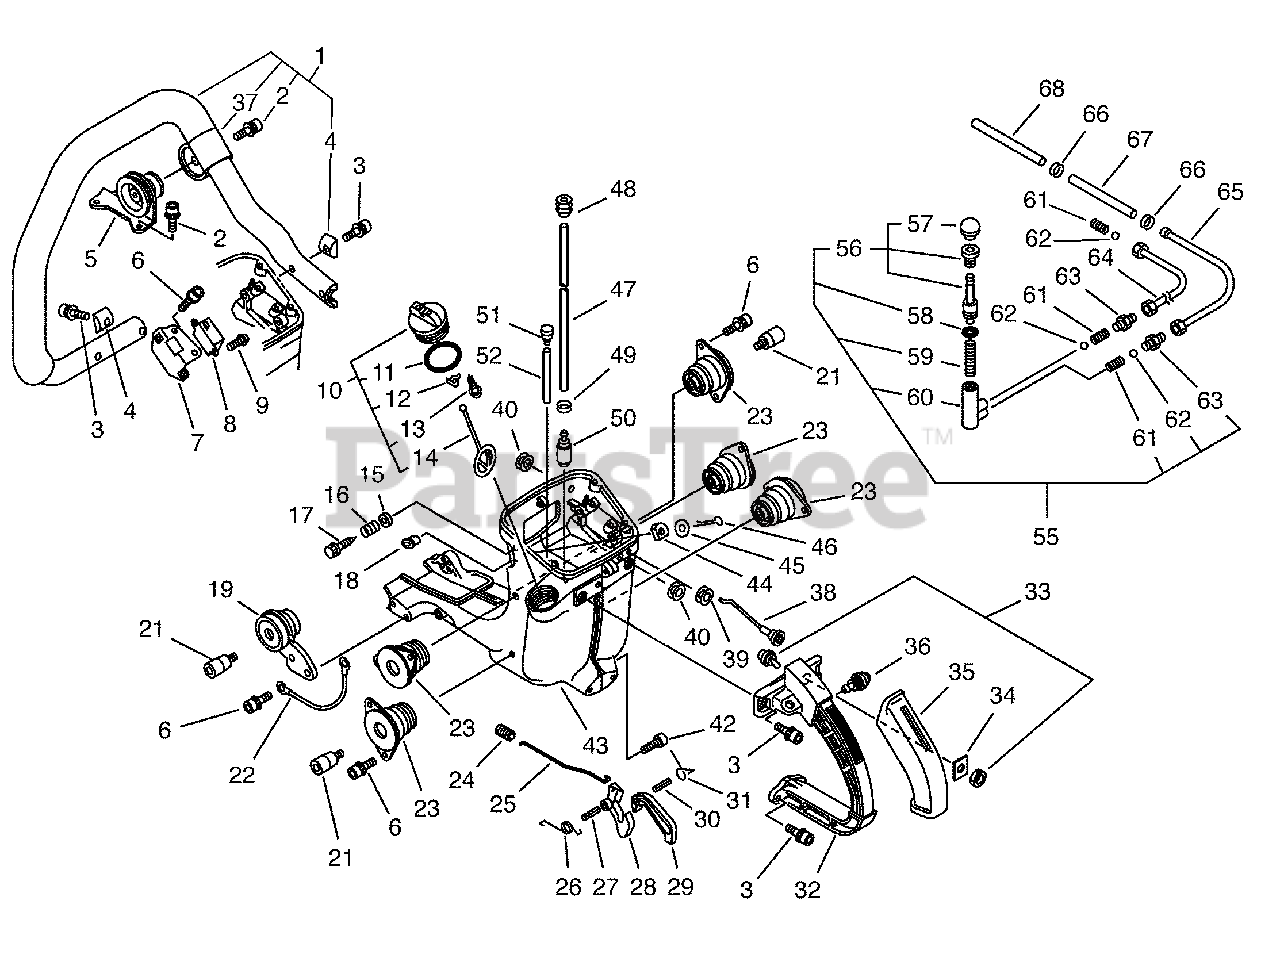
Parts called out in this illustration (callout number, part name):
1	HANDLE - FRONT
2	SCREW - 6X20
3	SCREW - 6X25
5	CUSHION
6	SCREW - 5X14
7	BRACKET
8	MODULE, E.S.G.
9	SCREW - 5X10
10	CAP ASSY
11	O-RING - 32
12	RETAINER
13	SCREW - 3X8
14	CONNECTOR, CAP
15	WASHER - 4
16	SPRING
17	SCREW, IDLE ADJUST
18	GROMMET
22	LEAD - GROUND
23	CUSHION
24	GROMMET
25	ROD, THROTTLE
26	SPRING, TRIGGER
27	PIN - SPRING -- 5X25
28	TRIGGER, THROTTLE
29	LOCKOUT, THROTTLE
30	PIN - SPRING -- 4X18
31	SPRING, LOCKOUT LEVER
33	IGNITION SWITCH KIT
34	LABEL - SWITCH
35	GRIP, HANDLE - REAR
36	LATCH, THROTTLE
37	BRACKET, HANDLE
38	ROD, CHOKE
40	BUSHING
42	SCREW - 5X14
43	TANK, FUEL
44	SEAL, FELT
45	WASHER - 2
46	PIN, SPLIT -- 2X15
47	PIPE - 3X6X360
49	CLIP - 6.5
50	FILTER, FUEL
51	VENT, FUEL TANK
52	PIPE - VENT
55	OIL PUMP ASSY
56	PISTON, OIL PUMP
57	BUTTON, OIL PUMP
58	O-RING - 6
59	SPRING, OIL PUMP
60	OIL PUMP BODY ASSY
61	SPRING, VALVE
62	VALVE, BALL
63	CONNECTOR
67	PIPE - FUEL
68	TUBE, PROTECTIVE
